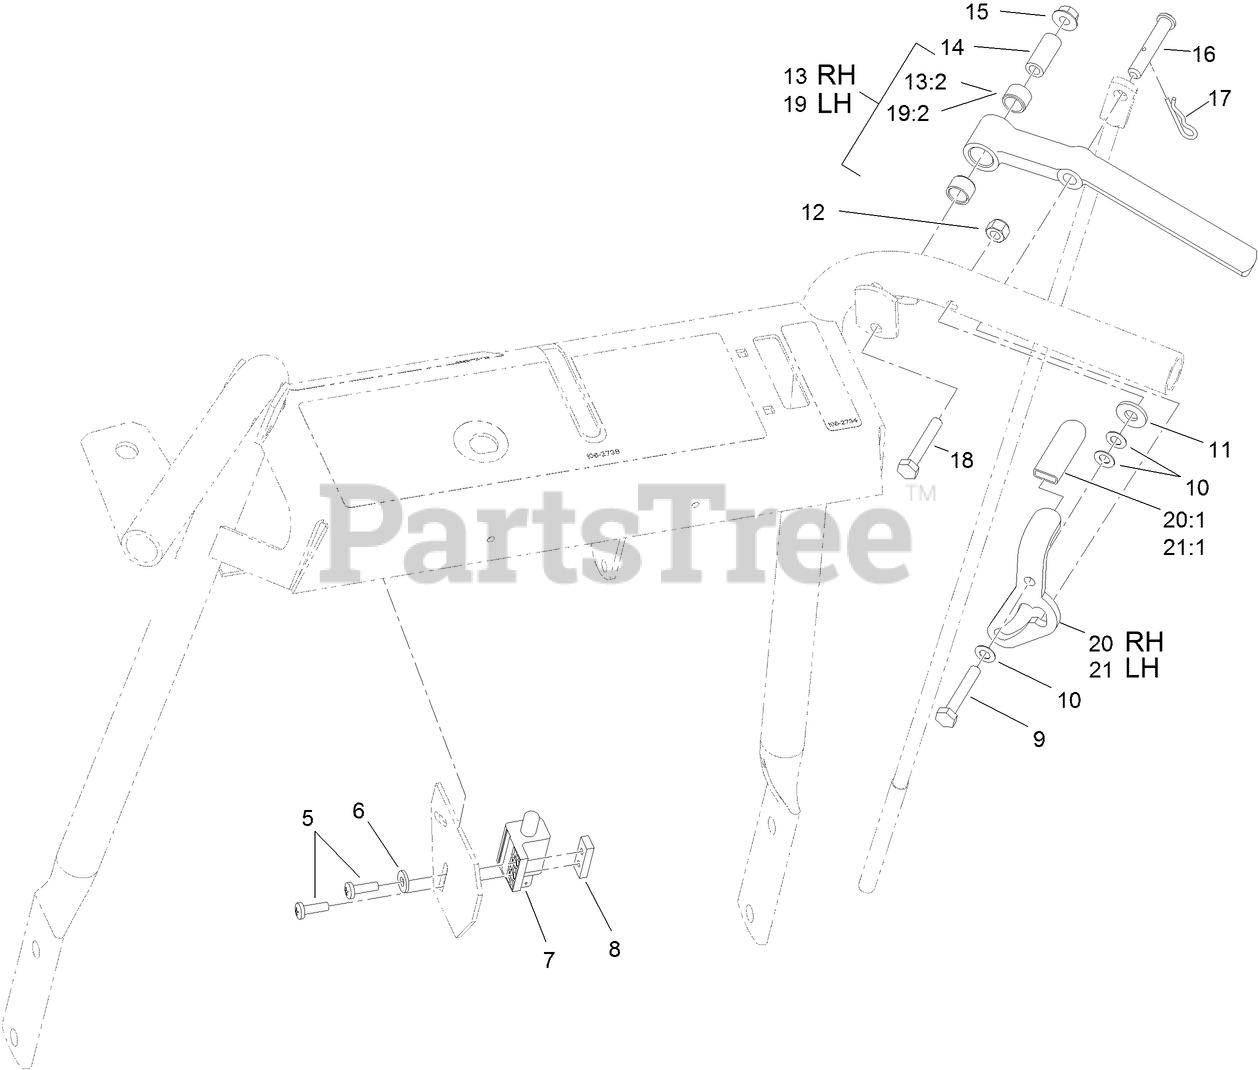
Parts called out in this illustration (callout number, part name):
5	SCREW-PPH
6	WASHER-FLAT
7	SWITCH-OPEN, NORMALLY
8	PLATE-TAPPED
9	SCREW-HH
10	WASHER-SPRING
11	WASHER-FLAT
12	NUT-LOCK, NI
13	RH Drive Lever ASM
13:2	BUSHING-SLEEVE
14	Bushing-Lever, Drive
15	NUT-HF
16	Pin-Clevis
17	PIN-COTTER
18	SCREW-HH
19	LH Drive Lever ASM
19:2	BUSHING-SLEEVE
20	RH LATCH and GRIP ASM
20:1	GRIP-LATCH
21	LH LATCH GRIP ASM
21:1	GRIP-LATCH
